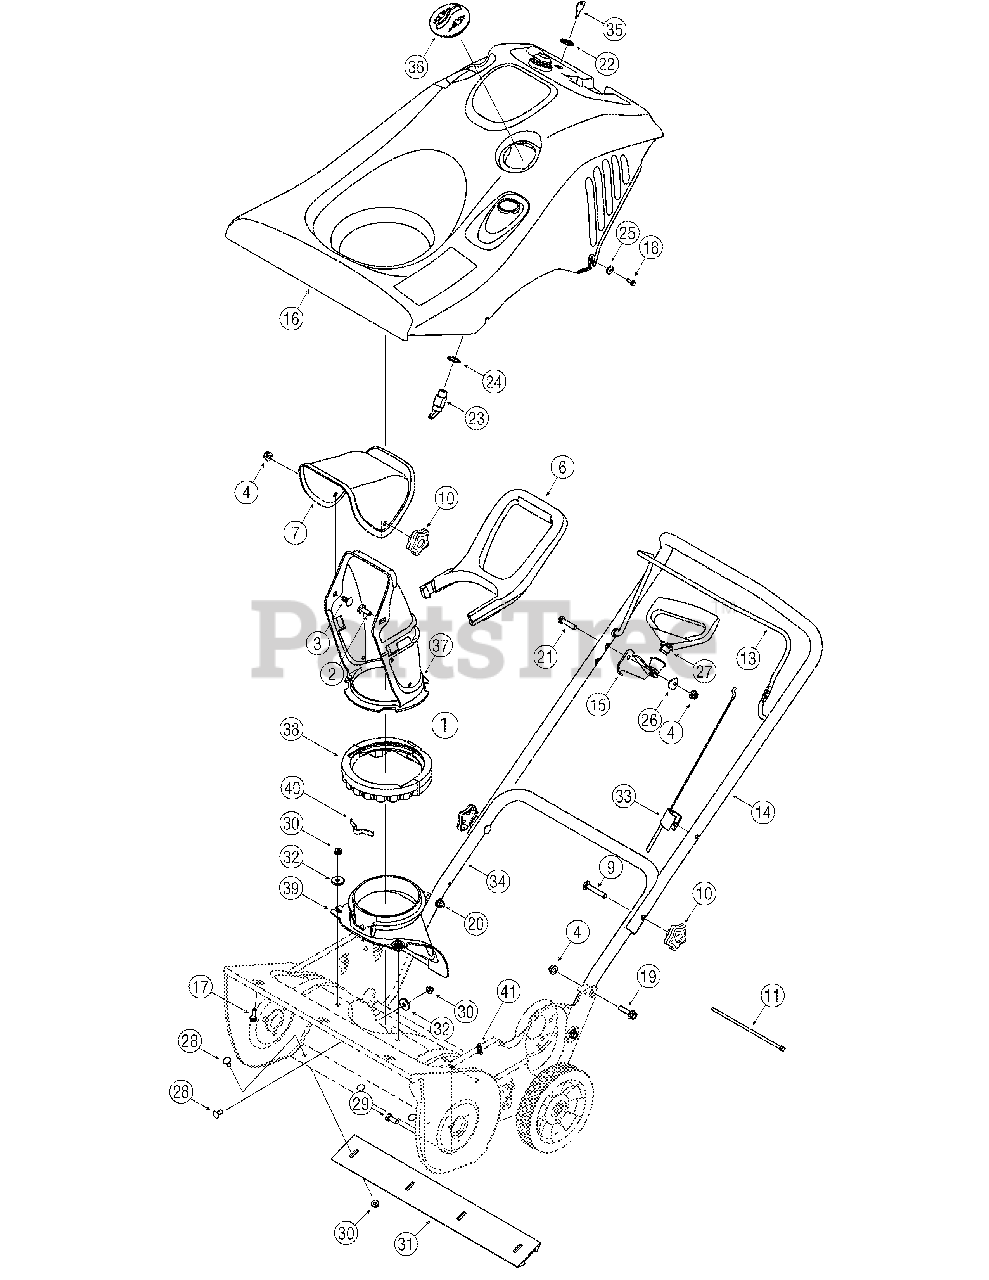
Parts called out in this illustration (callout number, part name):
1	Lower Chute Ass’y (Incl. #37-40)
2	Carriage Screw 5/16-18 x 1.0
3	Carriage Bolt 5/16-18 x .75
4	Flange Locknut 5/16-18 Gr. F, Nylon
6	Chute Handle
7	Upper Chute
9	Carriage Bolt 5/16-18 x 2.0 Gr. 5
10	Handle Knob Assembly
11	Cable Tie
15	Mitten Grip Bracket Ass’y
16	Shroud Yellow, Elec. Start
16	Shroud Black, Elec. Start, 5 HP
16	Shroud Grey, Elec. Start
16	Shroud Black, Elec. Start, 7 HP
17	Hex Tapp Scr 1/4 x .75" Lg.
18	Hex Wash B-Tapp Scr #10 x .62" Lg.
19	Hex Scr. .312-18 x 1.250
20	Hex Scr. 5/16-18 x 1.50 Gr. 5
21	Hex Scr. 5/16-18 x 1.375 Gr. 5
22	Hex Nut 5/8-32 x .12 Special
23	Key Switch-Electric Start
24	L-WasherInternal
25	Flat Washer .218" ID x .62" OD
26	Saddle Wash. .320 ID x .937 OD
27	Recoil Handle, Mitten
28	Carriage Bolt 1/4-20 x .62
29	Hex Bolt 5/16-18 x .75" Lg. Gr. 5
30	Hex L-Flanged Nut 1/4-20 Gr. F Nylon
31	Shave Plate
32	Flat Washer .25 ID x .93 OD x .125
33	Control Cable
35	Ignition Key
36	Spark Plug Cover
37	Lower Chute 5" Dia
38	Ring-Lower Chute
39	Chute Adapter 5" Dia
40	ChuteAdjustmentSpring
41	Extension Spring .33 OD x 1.12 Lg.
